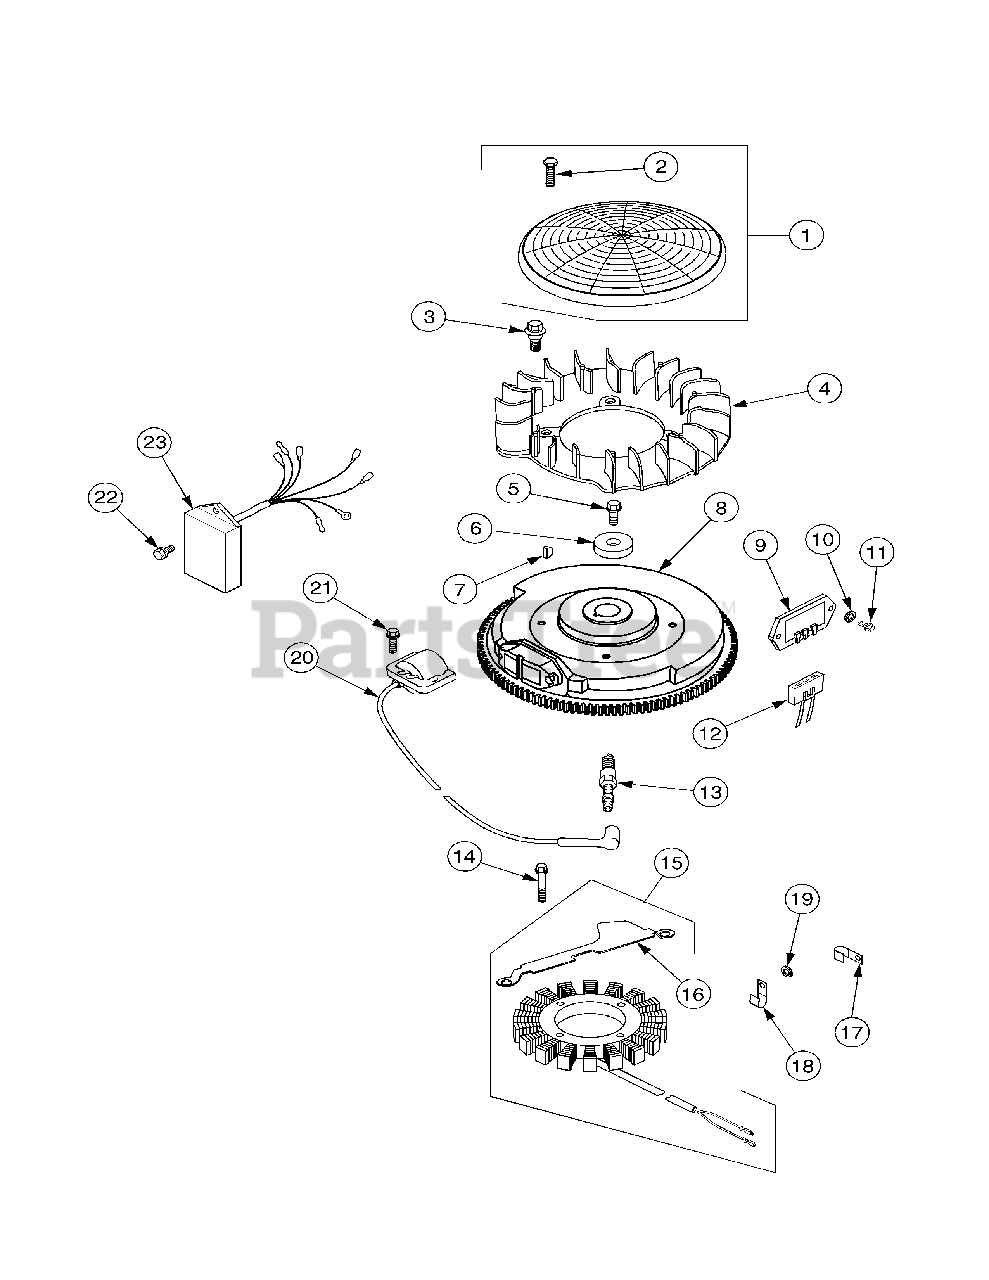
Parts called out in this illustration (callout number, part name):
1	Kit, Grass Screen
2	Screw, Hex Sems
3	Bolt, Shoulder
4	Fan
5	Screw, Hx Flange, M10-1.5 x 46
6	Washer, Plain, 3/8
8	Flywheel
9	Rectifier-Regulator
10	Washer, Plain, 3/16
11	Screw, Phillips Hd, 11-16 x 7/8
12	Connector
13	Spark Plug
14	Screw, Hx Cap, M5-0.8 x 25
15	Kit, 15 Amp Stator
16	Bracket, Stator Wire
17	Clip, Cable
19	Washer, Plain, 1/4
20	Module, Ignition
21	Screw, Hx Flange, M5-0.8 x 20
22	Module, Speed Advance
23	Screw, M4 x 0.7 x 10
